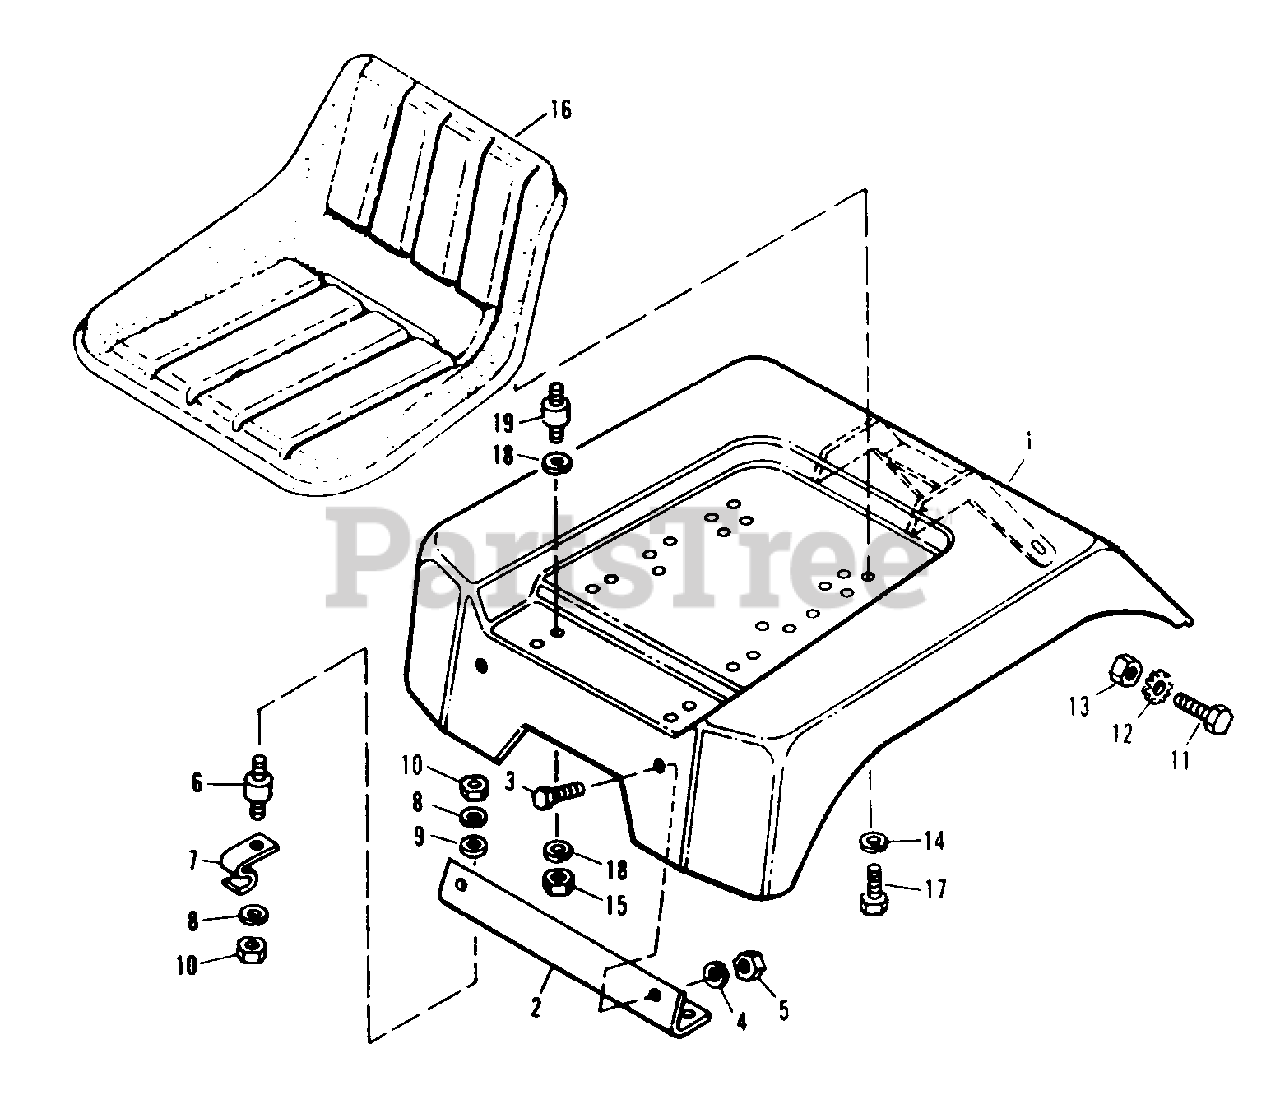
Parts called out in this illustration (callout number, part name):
1	Seat Deck Assy.
2	Seat Deck Bracket, Front
3	Hex Head Cap Screw, 5/16"-18 x 5/8"
4	Lock Washer, 5/16"
5	Hex Nut, Full, 5/16"-18
6	Cushion Connector, Front
7	Spring Clip
8	Lock Washer, 5/16"
10	Hex Nut, Full, 5/16"-18
11	Hex Head Capscrew, 3/8"-16 x 1-1/4"
12	Lock Washer
13	Hex Lock Nut, Full, 3/8"-16
14	Lock Washer, 5/16"
15	Hex Nut, Full, 5/16"-18
16	Contour Seat Assembly
17	Hex Head Capscrew, 5/16"-18 x 5/8"
18	Lock Washer, 5/16"
19	Cushion Connector
